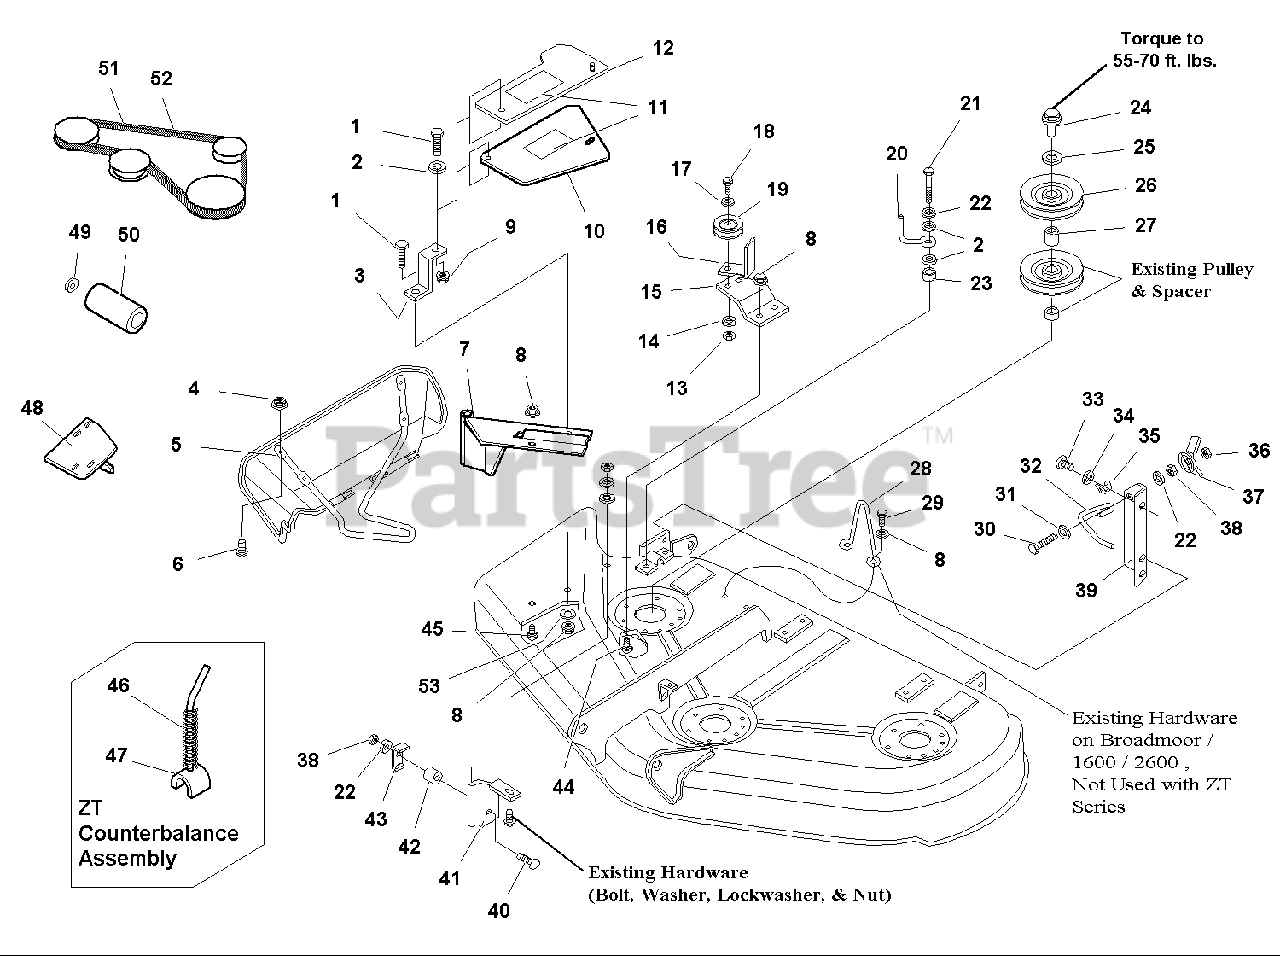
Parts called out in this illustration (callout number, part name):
1	CAPSCREW, Hex Hd, 5/16-18 x 1
2	WASHER, 5/16
3	SUPPORT, Belt Cover
4	NUT, Hex, Nylon Lock, #10-24
5	ROD, Deflector
6	SCREW, Truss Hd, #10-24 x 3/4
7	PIVOT ASSEMBLY
8	NUT, Hex Whizlock, 5/16-18
9	NUT, Nylock, Hex 5/16-18
10	COVER, Belt, 50" Models
11	DECAL, Warning
12	Cover, Belt, 44" Models
13	NUT, Hex, 3/8-16
14	LOCKWASHER, 3/8
15	BRACKET, Idler
16	LATCH, Belt Cover
17	WASHER, Flat, 3/8
18	CAPSCREW, Hex Hd 3/8-16 x 1-1/2
19	PULLEY ASSEMBLY, Idler, 2-3/4" OD
21	CAPSCREW, 5/16-18 x 1-1/2
22	LOCKWASHER, 5/16
24	NUT, Sleeve
25	WASHER, Belleville
26	PULLEY, 4-3/10" OD
27	HUB, Double Pulley, 1.16 Long
28	UPSTOP, Wire
29	CAPSCREW, Hex Washer Hd, Taptite, 5/16
30	CAPSCREW, Hex Hd, 5/16-18
31	WASHER, 5/16
32	LATCH, Spring
33	CAPSCREW, Hex Hd, 1/4-20 x 1/2
34	WASHER, 1/4
35	BELT STOP, (Height Indicator)
36	NUT, Hex Lock, 5/16-18
37	NUT,Wing, Special, 5/16
38	NUT, Hex, 5/16-18
39	BRACKET, Anchor
40	CARRIAGE BOLT, 5/16-18
41	BRACKET ASSEMBLY, Cutoff
44	CAPSCREW, Hex Hd, 5/16-18 x 7/8
45	CARRIAGE BOLT, 5/16-18 x 3/4
46	SPRING, Counterbalance
47	LEVER ASSY, Counterbalance
48	BRACKET, Mounting
49	PUSHNUT
51	V-BELT, 44" Turbo
52	V-BELT, 50" Turbo
53	WASHER, 3/8
